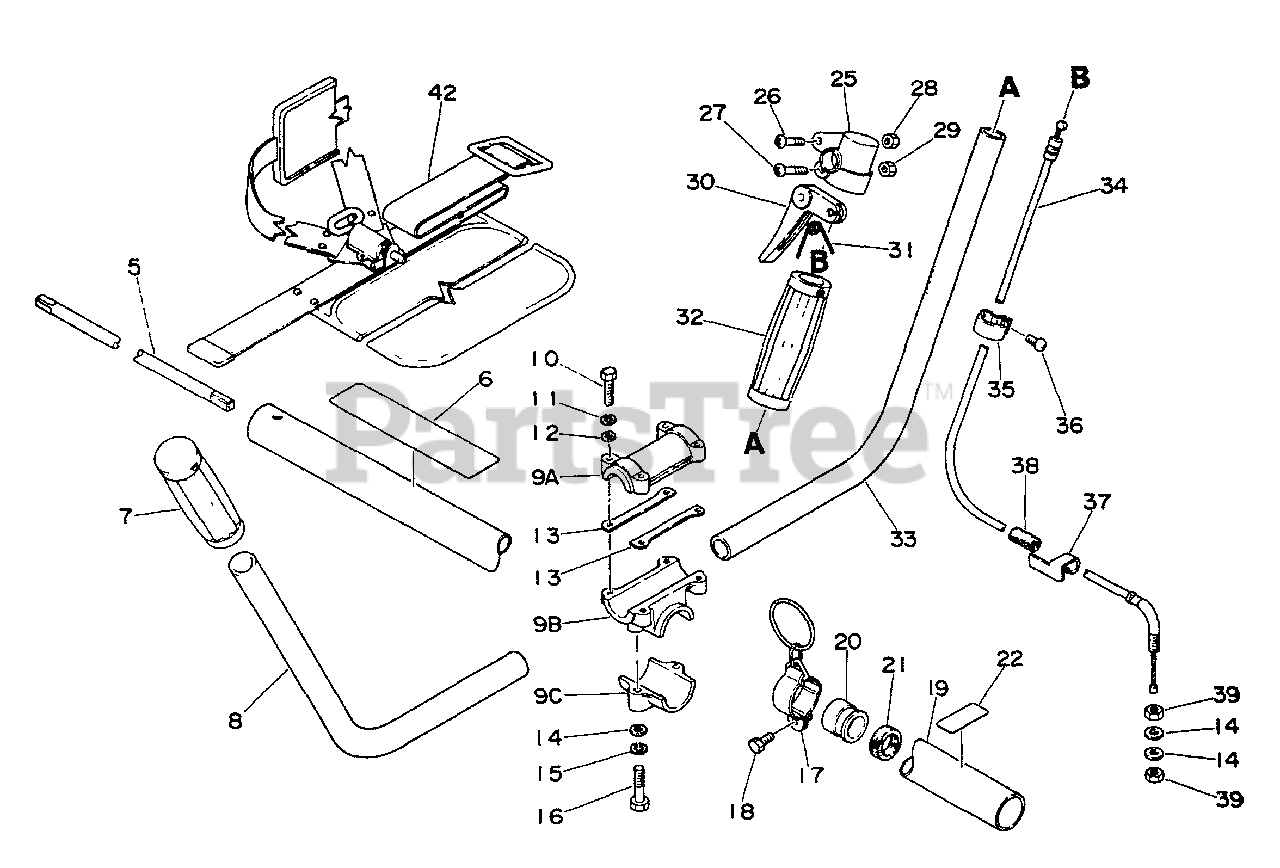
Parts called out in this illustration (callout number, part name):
5	DRIVESHAFT
6	LABEL - CAUTION
7	GRIP, HANDLE
8	HANDLE, LEFT
9	BRACKET ASSY, HANDLE
9A	BRACKET ASSY, HANDLE
9B	BRACKET ASSY, HANDLE
9C	BRACKET ASSY, HANDLE
10	BOLT - 5×25
11	WASHER, SPRING 6
12	WASHER, FLAT 5.5×10×0.8
14	WASHER 6.5×11.5×0.8
15	WASHER, SPRING 6
16	BOLT - 6×30
17	HANGER KIT
18	BOLT 5×12
19	MAIN PIPE ASSY
22	LABEL - ALIGNMENT
25	BRACKET, TRIGGER
27	SCREW 5×25
28	LOCKNUT - 5
29	NUT M5
30	TRIGGER, THROTTLE
32	GRIP, HANDLE
34	CABLE, THROTTLE
36	SCREW 5×10
38	TUBE
42	SHOULDER STRAP ASSY
